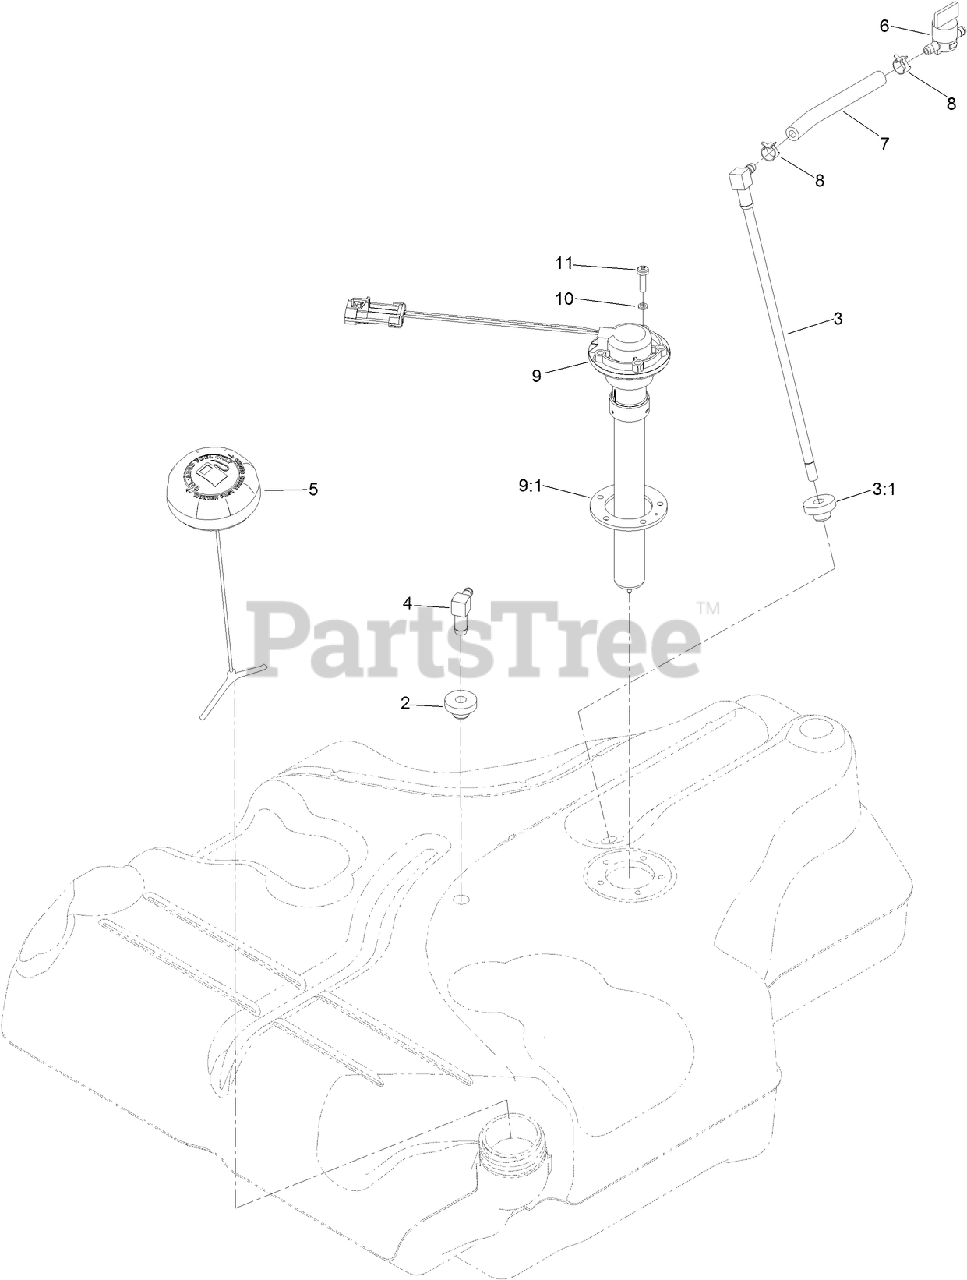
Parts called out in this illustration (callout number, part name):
2	BUSHING
3	FUEL LINE KIT (WITH GROMMET)
3:1	BUSHING
4	FITTING-90 ELBOW
5	CAP-FUEL, RATCHETING
6	VALVE-FUEL
7	HOSE-FUEL
8	CLAMP-HOSE
9	SENDER-FUEL
9:1	GASKET-SENDER, FUEL
10	WASHER-LOCK
11	SCREW-PAN
